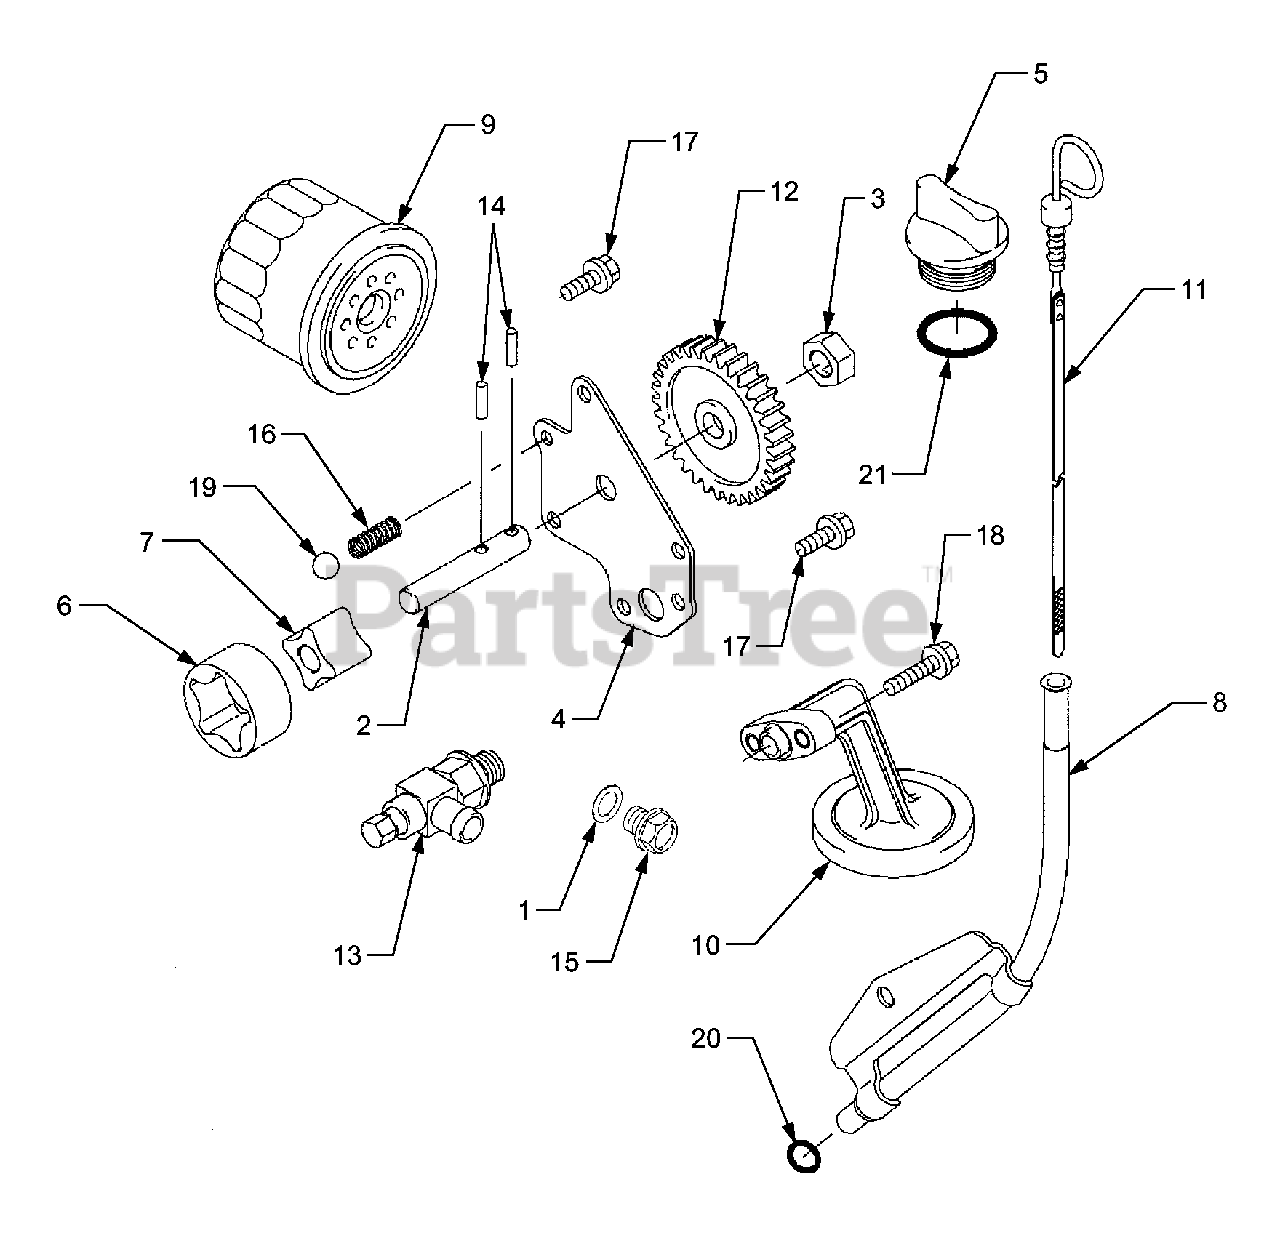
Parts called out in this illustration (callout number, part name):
1	Gasket, Drain Plug
2	Shaft, Oil Pump
3	Holder, Oil Pump
4	Cover, Oil Pump
5	Cap, Oil Filler
6	Rotor, Pump Outer
7	Rotor, Pump Inner
8	Pipe, Oil Gauge
9	Filter, Oil
10	Filter, Oil Suction
12	Gear, Spur, 33T
16	Spring
17	Bolt, Flanged
18	Bolt, Flanged
19	Ball, Steel
